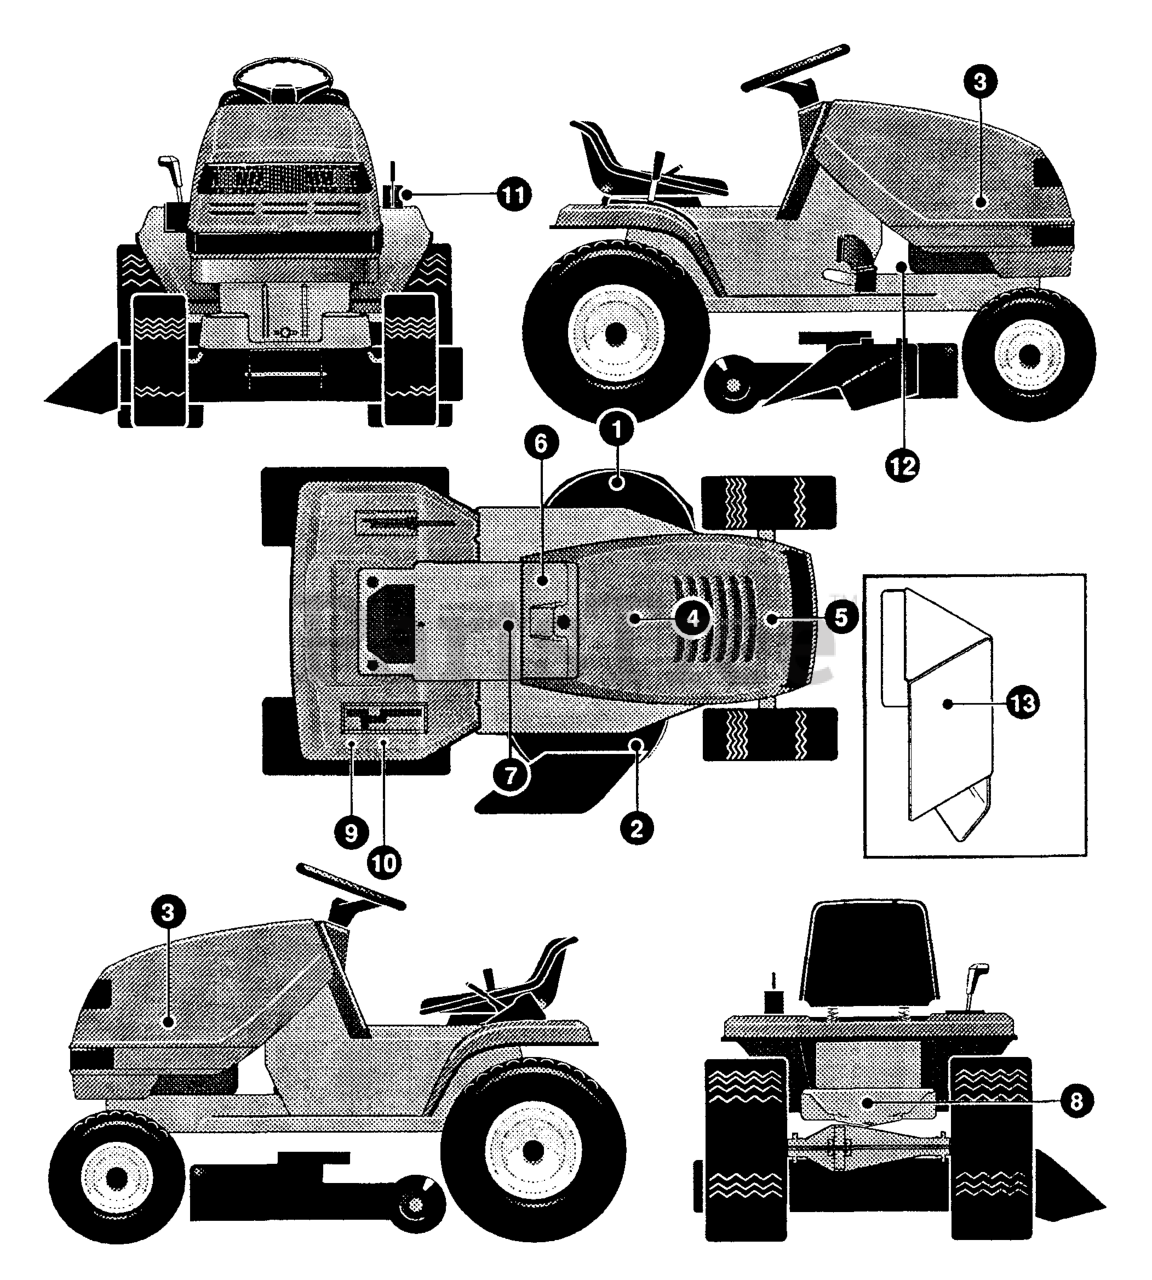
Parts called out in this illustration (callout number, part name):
1	DECAL, CAUTION DECK, LH
2	DECAL, CAUTION DECK, RH CUT HAND
3	PAD, 18 X 6 FOAM HOOD
4	PAD, 15 X 7 FOAM HOOD
5	PAD, 12 X 4 FOAM HOOD
6	DECAL, DASH
7	DECAL, CONSOLE CAUTION
8	DECAL, DRAWBAR WARNING
9	DECAL, SHIFT REV/NEUTRAL
10	DECAL, SHIFTER POSITION
11	DECAL, HEIGHT ADJUST
12	DECAL,BRAKE/CLUTCH
13	DECAL, HOT SURFACE WARNING
